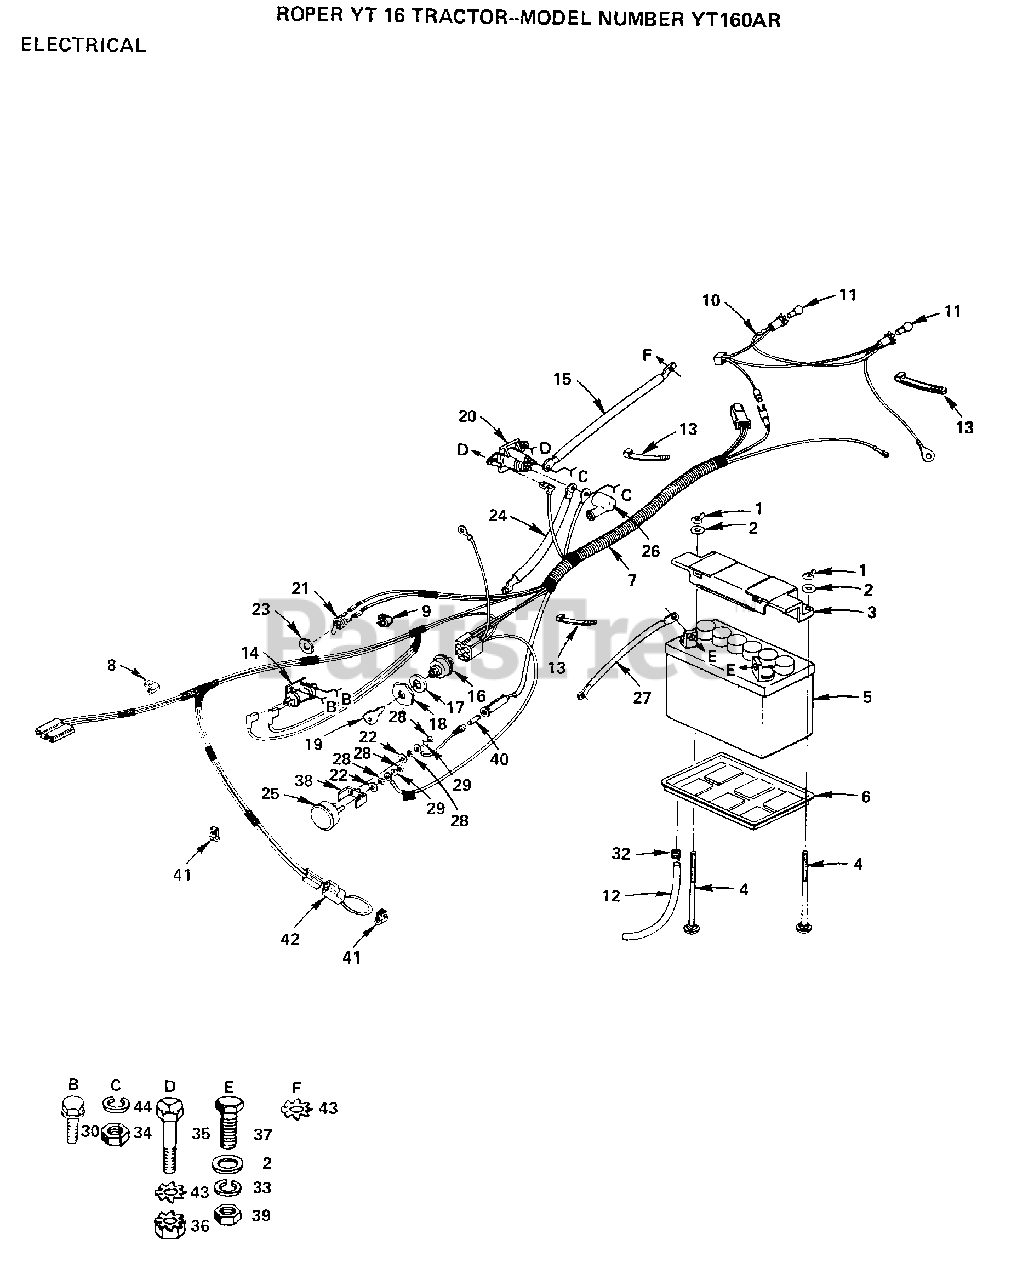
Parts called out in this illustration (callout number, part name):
2	WASHER
4	BOLT
6	"TRAY T, BATTERY"
8	CLIP GTV
10	HARNESS T
11	HEADLAMP BULB
13	WIRE TIE
17	LOCKWASHER
18	CONDUIT NUT L
21	LIGHT SWITCH T
24	CABLE-BATTERY T
25	AMMETER T
27	CABLE T
33	LOCKWASHER
34	NUT
35	BOLT
36	NUT
37	BOLT LT
40	FUSE-30 AMP
41	CLIPT
